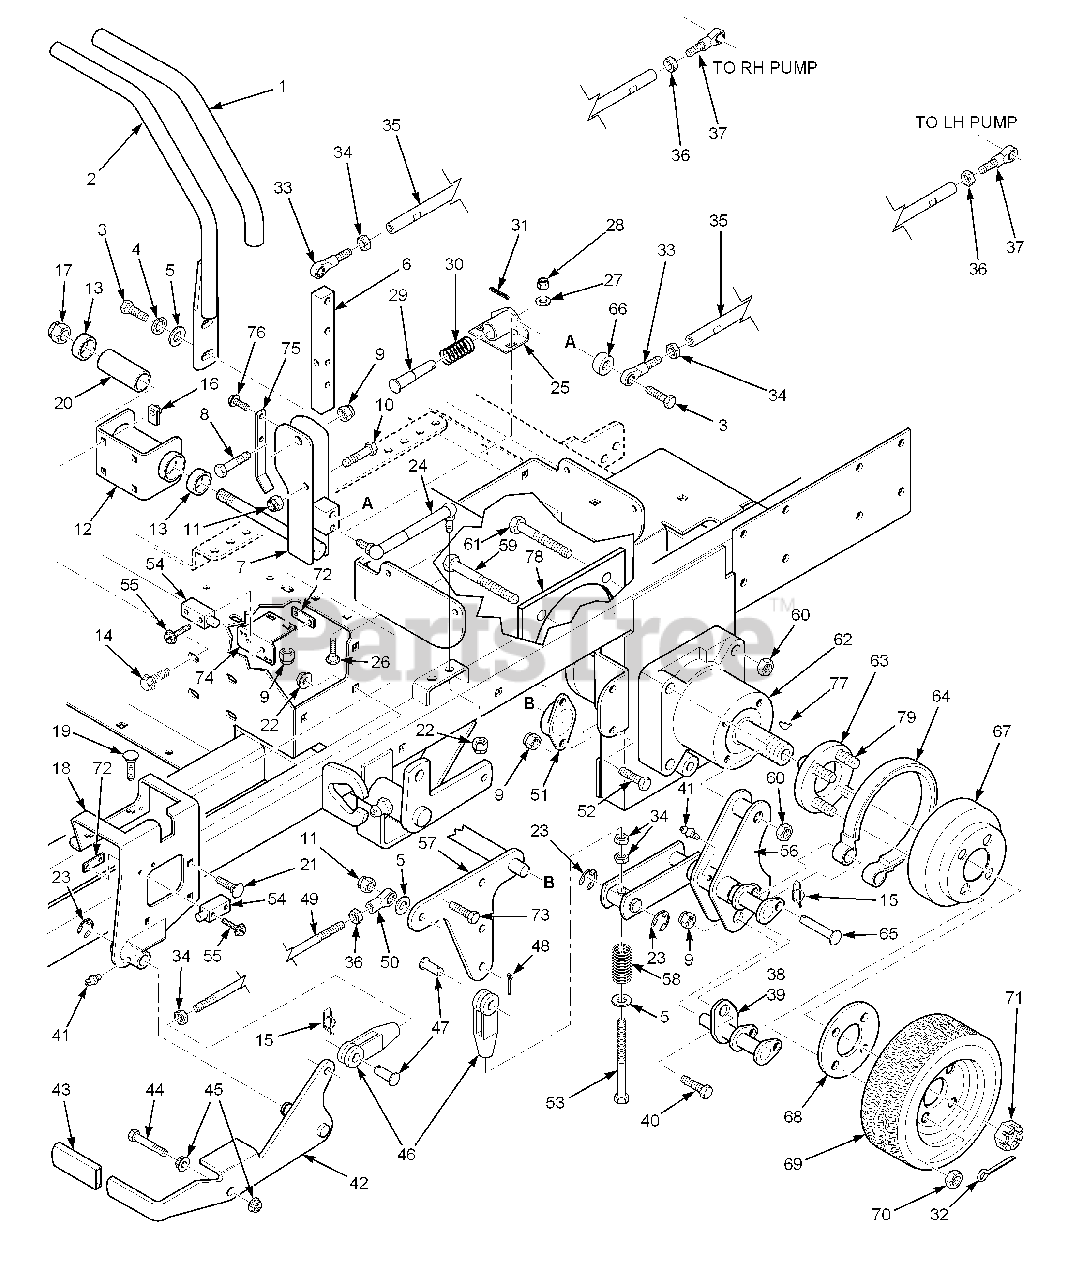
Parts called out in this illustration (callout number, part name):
1	Grip, Handle Bar
2	Handle Bar
3	Bolt, Hex Head 3/8-16 x 1-1/4"
4	Lockwasher, 3/8"
5	Flatwasher. 3/8"
6	Bar, Control Lever
7	Control Lever
8	Bolt, Hex Head 5/16-18 x 2"
9	Nut, Hex Elastic Stop 5/16-18
10	Bolt, Hex Head 3/8-16 x 2"
11	Nut, Hex Elastic Stop
12	Bracket, Control
13	Ball Bearings, Neutral Return
14	Bolt, Hex Head 5/16-18 x 1-1/4"
15	Pin, Rue Cotter 3/8 Dia.
16	U-Nut, 5/16-18
17	Nut, Hex Elastic Stop 5/8-11
18	Bracket, Control Lever LH
19	Bolt, Carriage 5/16-18 x 1"
20	Spacer, Bearing
21	Bolt, Carriage 5/16-18 x 3/4"
22	Nut, Hex Serrated Flange 5/16-18
23	Ring, Retaining 5/8" External "E"
24	Gas Damper
25	Bracket, Neutral Return
26	Bolt, Carriage 1/4-20 x 3/4"
27	Flatwasher, 1/4"
28	Nut, Hex Elastic Stop 1/4-20
29	Pin, Retaining Spring
30	Spring
31	Roll Pin, Spring 5/32 x 3/4"
32	Pin, Cotter 9/16 x 1-1/2"
33	Rod End, Male 3/8-24 RH Thread
34	Nut, 3/8-24 RH Thread
35	Tube, Control Link
36	Nut, Hex 3/8-24 LH Thread
37	Rod End, Male 3/8-24 LH Thread
38	Brake Linkage Weldment LH
39	Brake Linkage Weldment RH
40	Bolt, Hex Head 5/16-18 x 1"
41	Grease Fitting
42	Lever, Parking Brake
43	Grip, Parking Brake
44	Bolt, Hex Head 3/8-16 x 2-3/4"
45	Nut, Hex Serrated Flange 3/8-16
46	Clevis, Traction Control
47	Pin, Clevis 3/8-16 x 1-1/16"
48	Pin, Cotter 3/32 x .75
49	Rod, Parking Brake
50	Rod End, LH Thread
51	Bushing, Self Align
52	Bolt, Hex Head 5/16-18 x 3/4"
53	Bolt, Hex Head 3/8-24 x 5-1/4", 2-3/4" Thread
54	Switch
55	Screw, Hex SLTD WSHR Head #10-32 x 3/4"
56	Brake Linkage, LH
57	Bellcrank, Brake Actuator
58	Spring
59	Bolt, Hex Head 1/2-13 x 3-1/2"
60	Locknut, Hex 1/2-13 Center Lock
61	Bolt, Hex Head 1/2-13 x 2-1/2"
62	Wheel Motor, Ross
63	Wheel Hub Assembly
64	Brake Band Assembly
65	Pin, Clevis 3/8" Dia. x 2"
66	Spacer
67	Brake Drum
68	Spacer, Wheel
69	Wheel Assembly 23 x 10.5-12
69	Rim W/Valve Stem
69	Tire, 23 x 10.5-12
69	Wheel Assembly 24 x 12-12 Turf Master
69	Tire, 24 x 12-12 Turf Master
70	Lug Nut, 1/2-20
71	Nut, Hex Castle
72	Plate, Threaded
73	Bolt, Hex Head 3/8-16 x 1-1/2"
74	Bracket, Switch Mounting
75	Bracket, Switch Actuator
76	Bolt, Hex Serrated Flange 5/16-18 x 3/4"
77	Key, Woodruff 5/16 x 1"
78	Plate Weldment, Motor Backing
79	Lug Bolt, 1/2-20 x 1.938"
